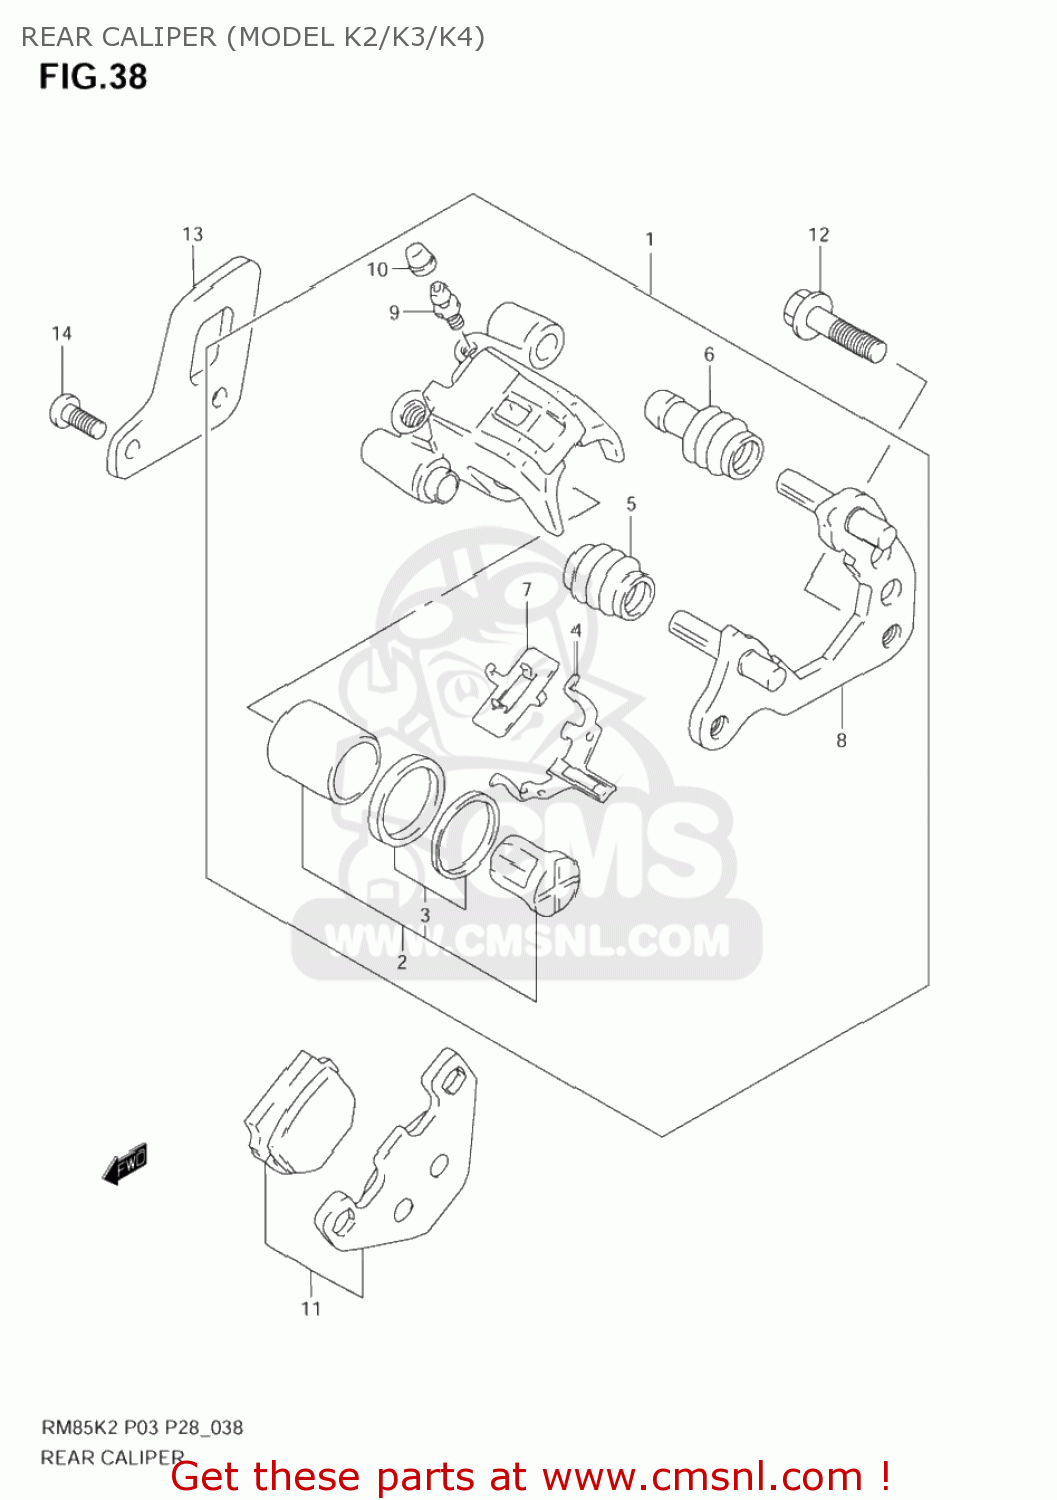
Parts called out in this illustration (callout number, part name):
1	CALIPER ASSY,RR
2	PISTON SET
3	SEAL SET,PISTON
4	SPRING,PAD
5	BOOT,AXLE
6	INSULATOR,AXLE
7	SHIM
8	CARRIER,CALIPER
9	BLEEDER
10	CAP,BLEEDER
11	PAD SET (NAS)
12	BOLT(8X18)
13	GUARD,RR CALIPER
14	SCREW(6X12)
